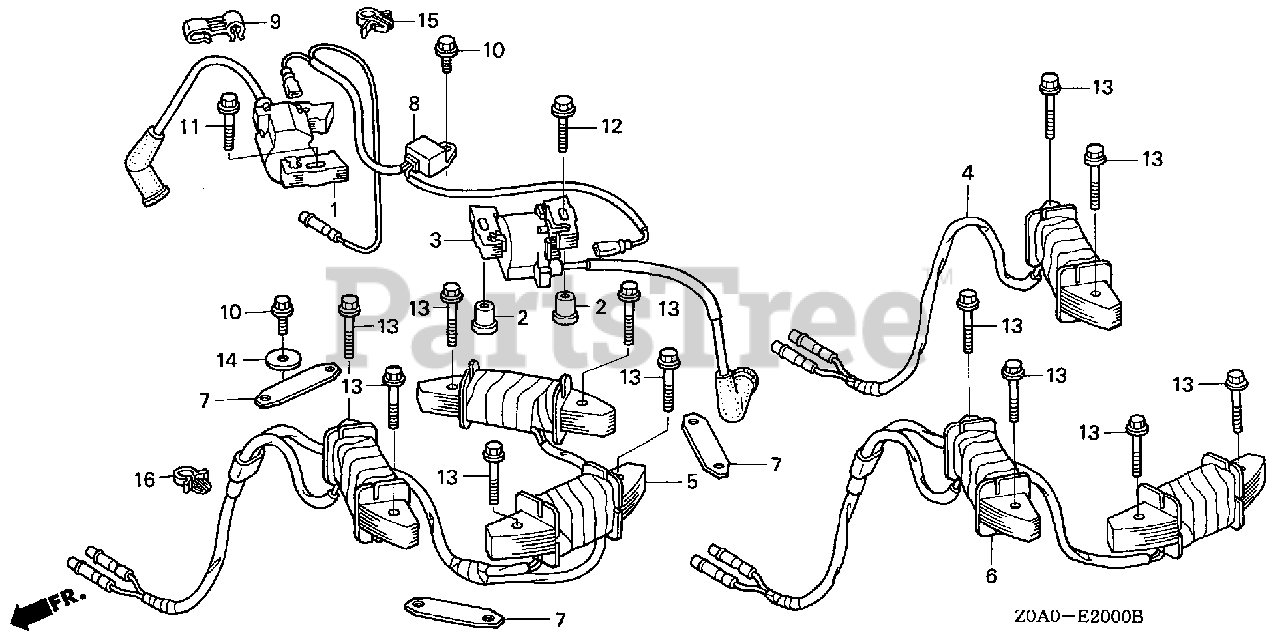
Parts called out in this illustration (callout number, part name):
1	COIL ASSY., IGNITION (#1)
2	COLLAR, IGNITION COIL
3	COIL ASSY., IGNITION (#2)
4	COIL ASSY., CHARGE (12V/3A)
8	DIODE ASSY., ENGINE STOP
9	CLAMP, CENTER WIRE
10	BOLT, FLANGE (6X12) (CT200)
11	BOLT, FLANGE (6X28)
12	BOLT, FLANGE (6X45) (CT200)
13	BOLT, FLANGE (6X32)
14	WASHER, TANK SETTING
15	CLIP, WIRE HARNESS (6MM) (WHITE)
16	CLIP, WIRE HARNESS
